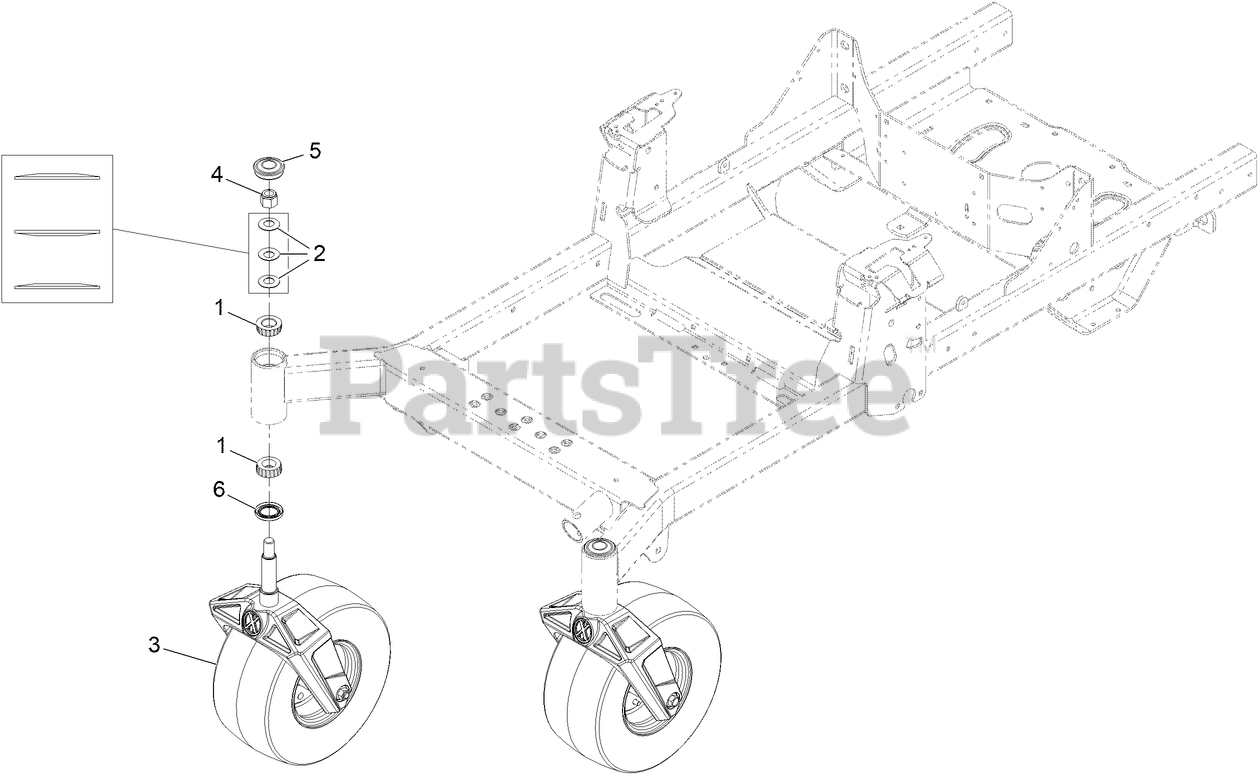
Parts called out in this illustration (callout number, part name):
1	Cone-Bearing Tapered Roller
2	WASHER-BELLVILLE
3	ASM-FRONT CASTOR W/FORK
4	NUT-LOCK, NI
5	CAP, GREASE
6	SEAL-GREASE
